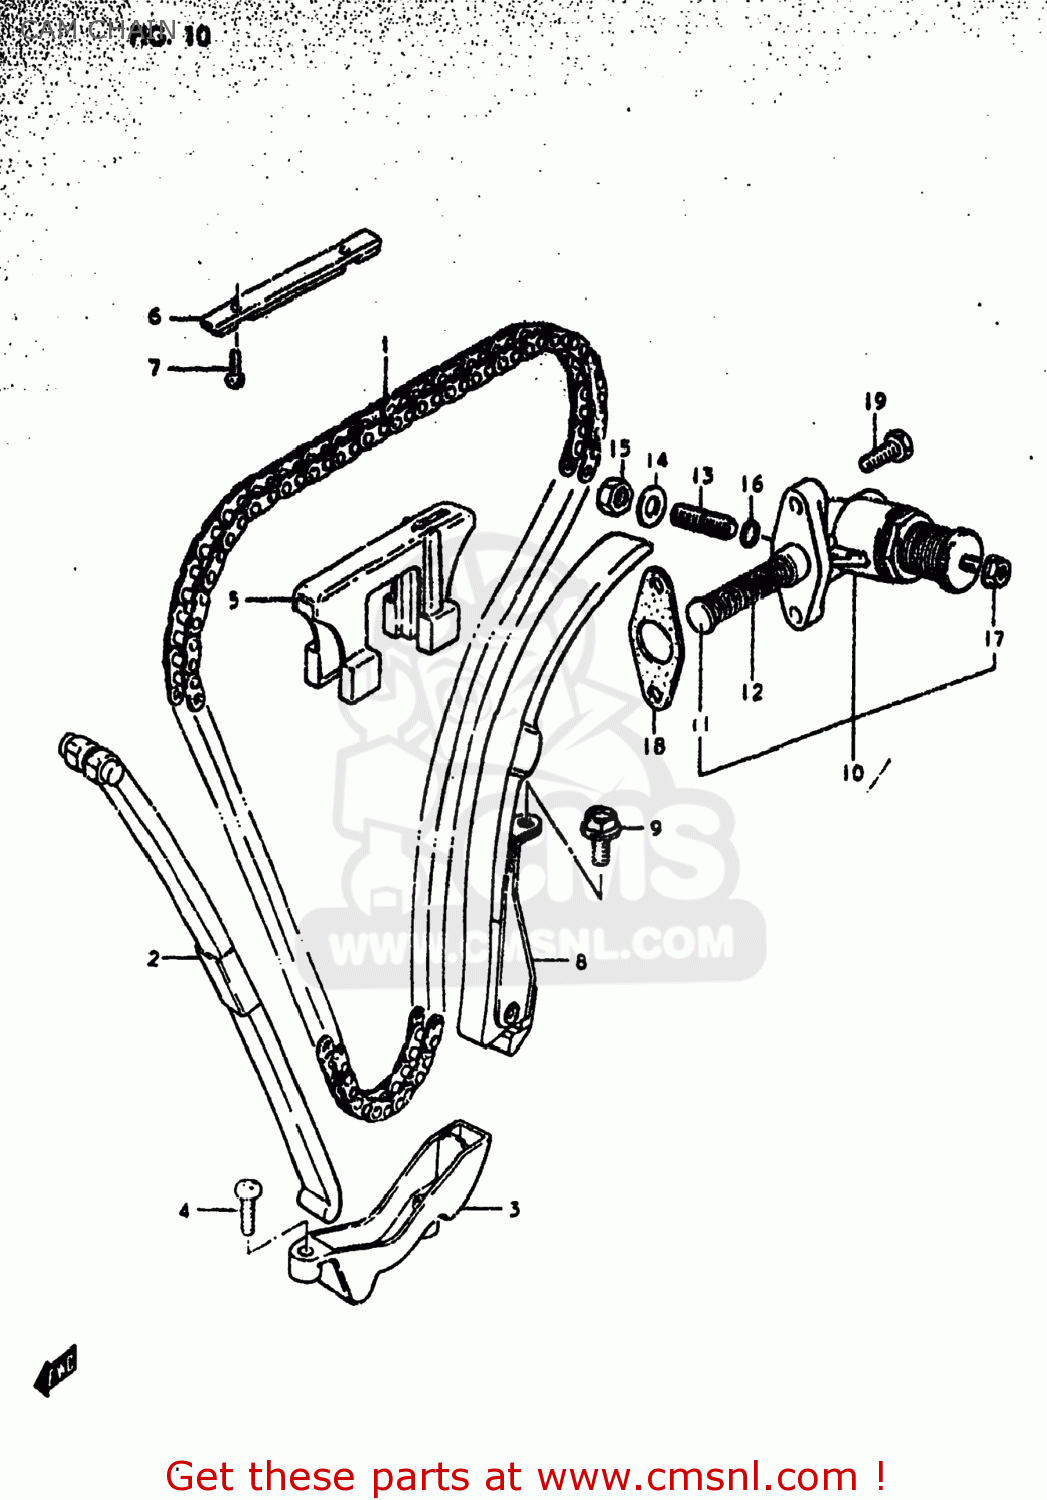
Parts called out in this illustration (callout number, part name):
1	CHAIN,CAMSHAFT DRIVE
2	GUIDE,CAM CHAIN NO.1
3	HOLDER,CAM CHAIN GUIDE
4	SCREW
5	GUIDE,CAM CHAIN NO.2
6	GUIDE,CAM CHAIN NO.3
7	SCREW
8	TENSIONER,CAM CHAIN
9	BOLT
10	ADJUSTER ASSEMBLY,TENSIONER
11	ROD,PUSH
12	SPRING
13	SCREW
14	WASHER
15	NUT
16	O-RING
17	NUT
18	GASKET,TENSIONER ADJUSTER (MCA)
19	SCREW
